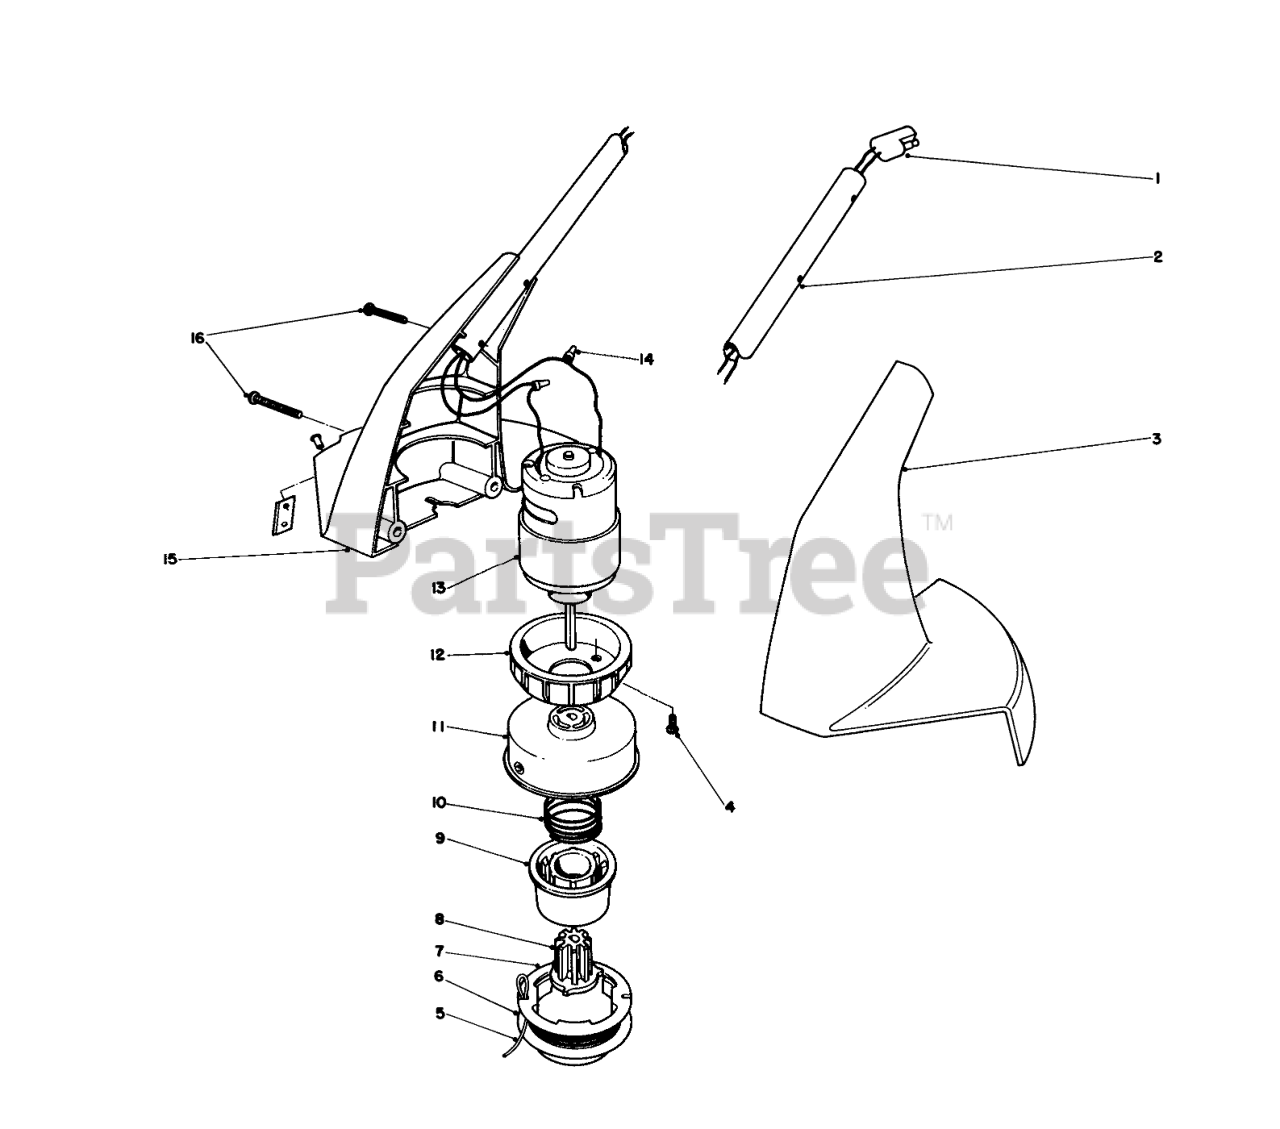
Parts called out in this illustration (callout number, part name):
1	WIRING HARNESS LOWER
2	EXTENSION HANDLE
3	Housing-L.H.
4	SCREW 8 - 32 X 250
5	.040" Cutting Line in Coil
6	SPOOL CAP
7	Prewound Spool
8	Driver
9	CORE - SPOOL
10	Spring
11	Drum (including eyelet)
12	Heat Sink Casting
13	Motor
14	Wire Connector
15	R.H. Motor Housing (Incl. Ref. #17&18)
16	SCREW-PLASTITE
